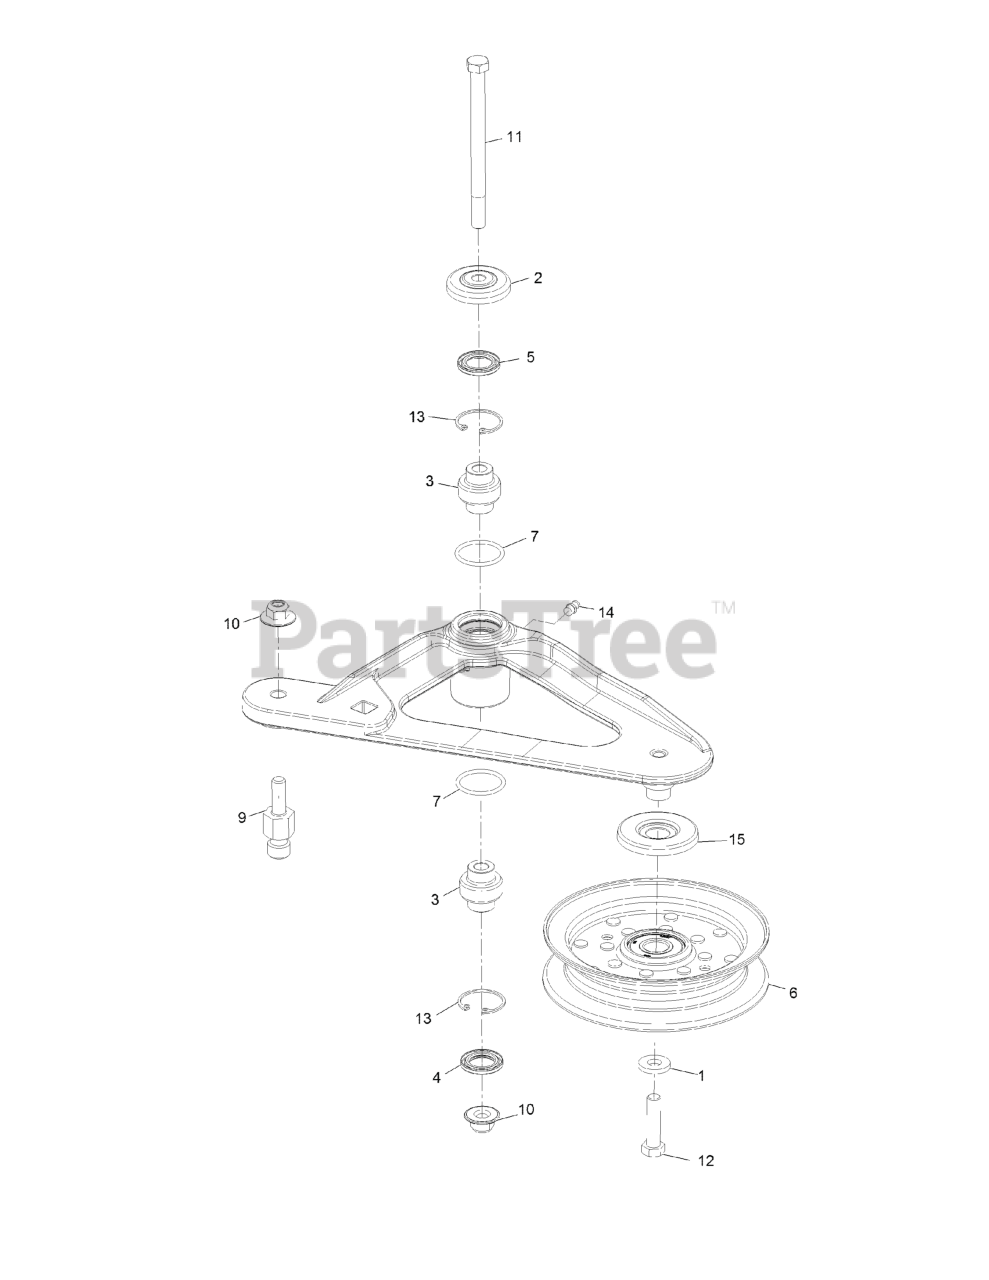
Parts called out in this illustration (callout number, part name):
2	GUARD-TOP
3	BEARING-SPHERICAL
4	SEAL-LIP, DOUBLE
5	SEAL-LIP, SINGLE
6	IDLER-PULLEY, FLAT
9	PIN-SPRING, ANCHOR
10	Nut-Nyloc 3/8-16 Flg
11	SCREW-SHOULDER, HH
12	SCREW-HH
13	RING-SNAP
14	FITTING-GREASE
15	SHIELD-GUARD, DUST
